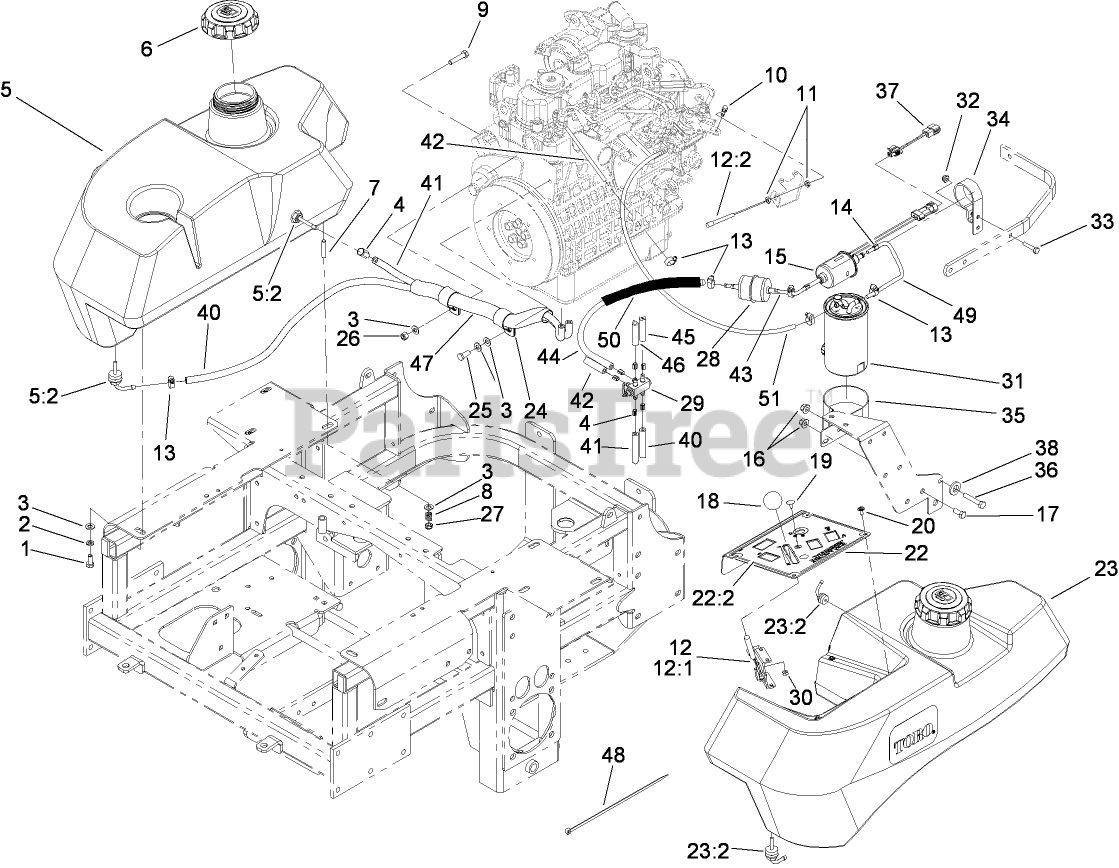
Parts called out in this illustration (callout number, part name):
1	SCREW-HH
2	WASHER-LOCK
3	WASHER-PLAIN
4	CLAMP-HOSE, FUEL
5	RH FUEL TANK ASM
5:2	Fitting-Fuel, Bulkhead
6	CAP-FUEL, DIESEL
8	SPRING-TANK, FUEL
9	SCREW-HH
10	SWIVEL-STOP, CABLE
11	NUT-JAM
12	CABLE-CONTROL, THROTTLE
12:1	LEVER-CABLE, THROTTLE
12:2	CABLE-THROTTLE
13	CLAMP-WORM
14	CLAMP-HOSE, FUEL
15	PUMP-FUEL
16	NUT-LOCK, NI
17	SCREW-HH
18	KNOB-BALL
19	BOLT-CARR
20	SCREW-PPH
22	CONTROL PANEL ASM
22:2	DECAL-PANEL, CONTROL
23	LH FUEL TANK ASM
23:2	Fitting-Fuel, Bulkhead
24	CLIP-LOOM
25	SCREW-HH
26	NUT-LOCK, NI
27	NUT-LOCK, NI
28	FILTER-INLINE
29	VALVE-FUEL, DUAL FLOW
30	NUT-LOCK, NI
31	ELEMENT-FILTER, FUEL/WATER
32	NUT-HF
33	SCREW-HH
34	BRACKET-PUMP, FUEL
35	BRACKET-FILTER, FUEL
36	SCREW-HH
37	HARNESS-WIRE
38	WASHER-FLAT
40	HOSE-FUEL
41	HOSE-FUEL
42	HOSE-FUEL
43	HOSE-FUEL
44	HOSE-FUEL
45	HOSE-FUEL
46	HOSE-FUEL
47	SLEEVE-FABRIC
48	TIE-PLASTIC
49	HOSE-FUEL
50	CONDUIT-FUEL LINE
51	HOSE-FUEL
